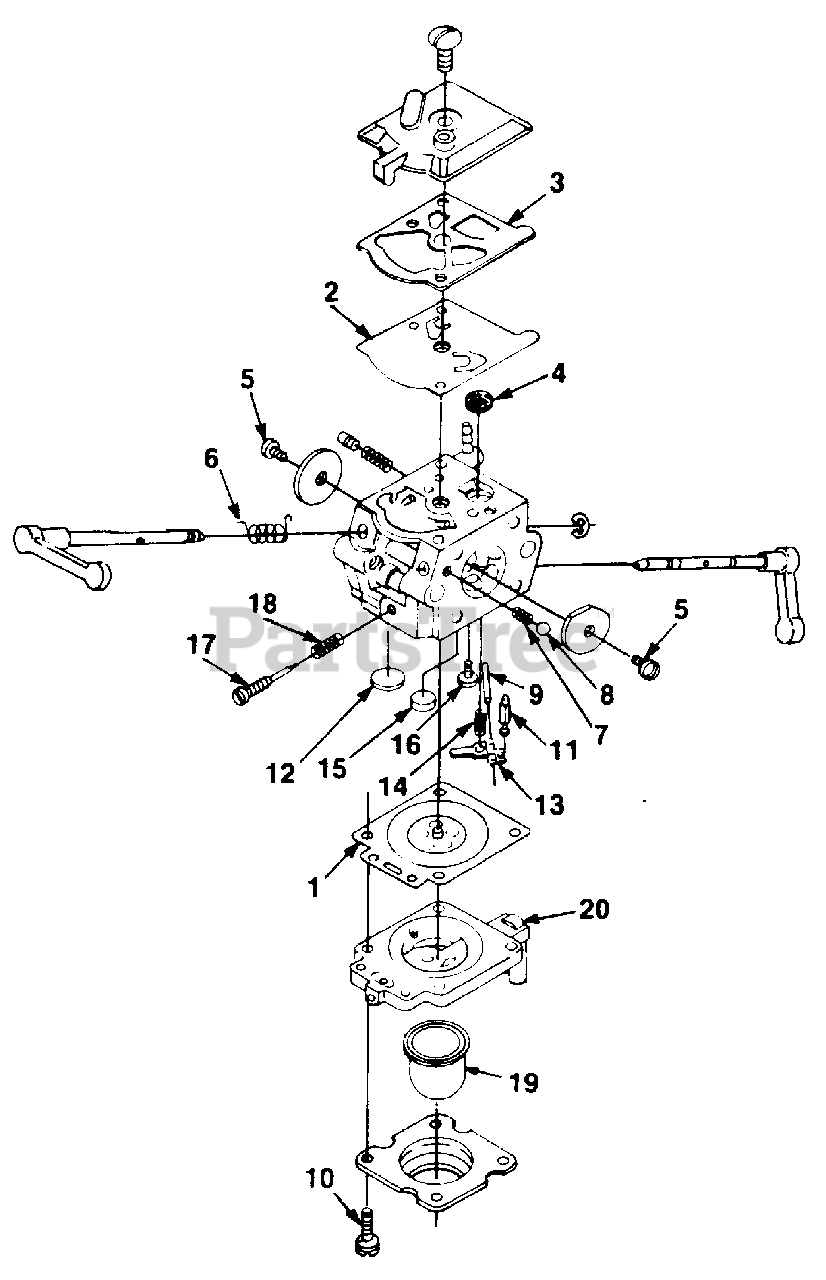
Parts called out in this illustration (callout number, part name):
1	Gasket Kit
2	Gasket Kit
3	Gasket Kit
4	Repair Kit
5	Repair Kit
6	Repair Kit
7	Repair Kit
8	Repair Kit
9	Repair Kit
10	Repair Kit
11	Repair Kit
12	Repair Kit
13	Repair Kit
14	Repair Kit
15	Repair Kit
16	Repair Kit
17	Repair Kit
18	Repair Kit
19	Primer Bulb
20	Primer Base
